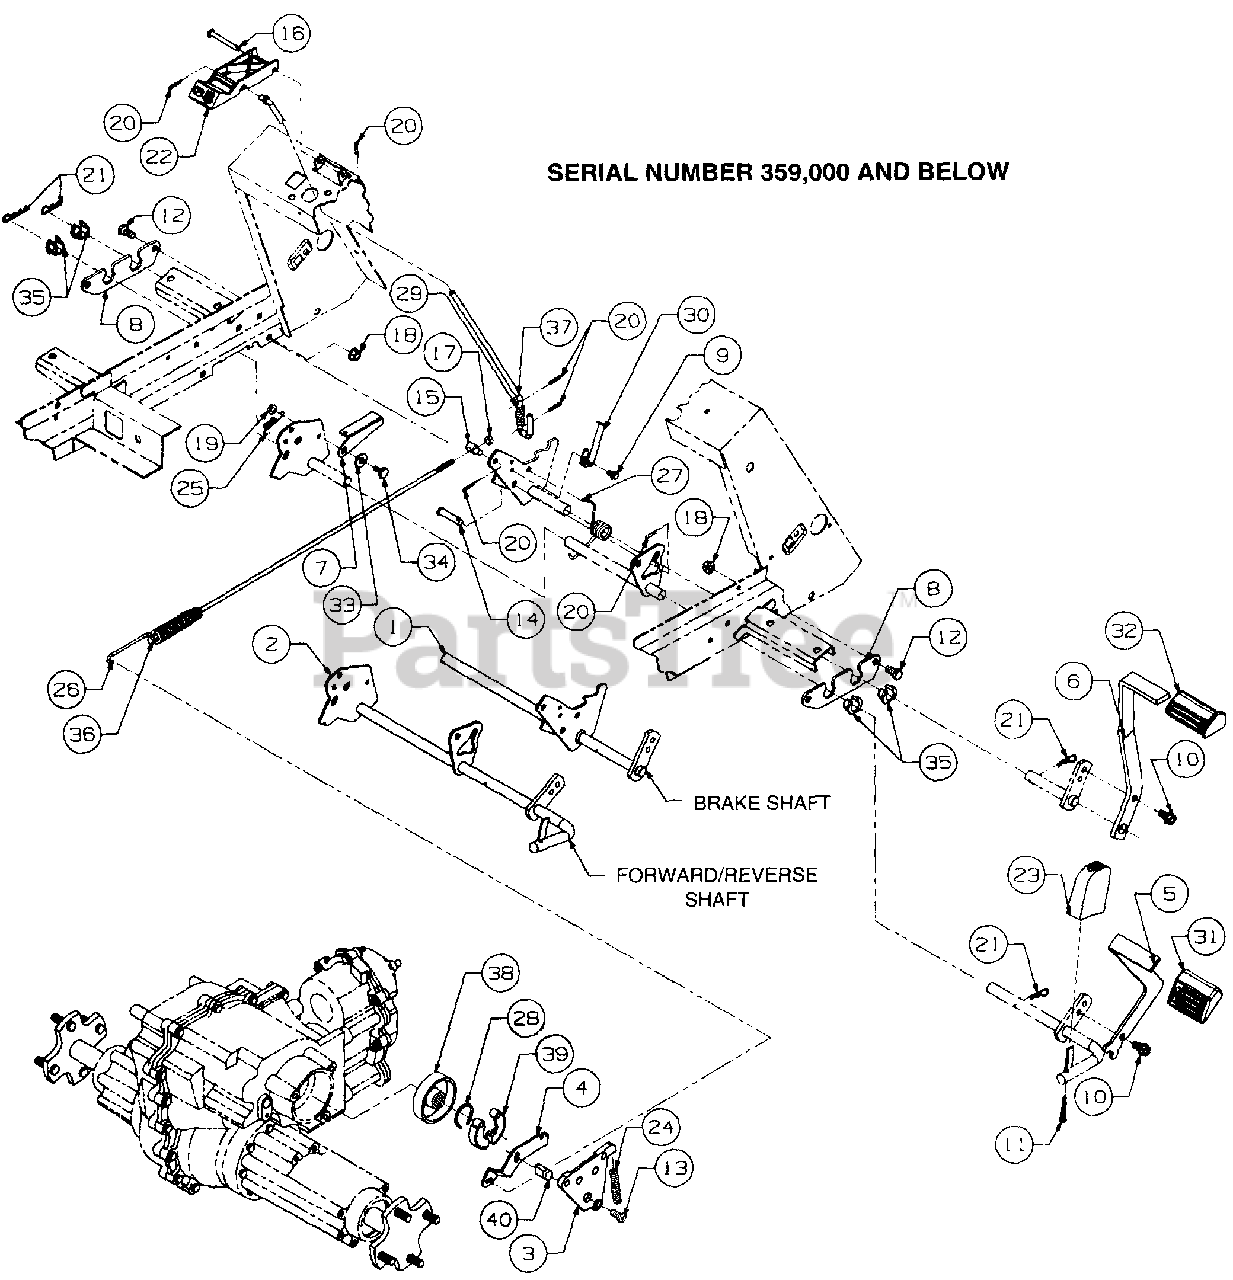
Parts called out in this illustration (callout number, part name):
1	Shaft Assy, Brake
2	Shaft Assy, Forward/Reverse
3	Plate, Brake
4	Arm, Brake
7	Actuator, Reverse Switch
8	Plate, Bearing Mounting
9	Screw, Hex Wash Tapp, 1/4 x .50 Lg
10	Screw, Hex Wash TT-Tapp, 3/8-16 x .75 Lg
11	Screw, Truss Mach Tapp, #12 x 1.5
12	Screw, Hex Cap, 3/8-16 x .75 GR5
13	Screw, Low Hd Cap, 3/8-16 x .75
14	Pin, Clevis, 3/8 OD x 1.62 Lg
15	Ferrule, Adjustment
16	Pin, Clevis, 1/4 OD x 2.38 Lg
17	Nut, Hex Sems, 1/4-20
18	Nut, Hex Flanged Lock, 3/8-16
19	Nut, Hex Flange Lock, 1/4-20
20	Pin, Internal Cotter, 5/16 Dia x 1.12
21	Pin, Internal Cotter, 3/8 Dia x 1.625
22	Lever, Park Brake
23	Pad, Reverse Pedal
24	Spring, Compression
25	Spring, Extension, .38 OD x 2.10 Lg
26	Spring, Extension, .75 OD x 5.0 Lg
27	Spring, Torsion
28	Spring, Brake
29	Spring, Compression, .5 OD x 2.23
30	Actuator, Neutral Switch
31	Pad, Forward Pedal
32	Pad, Brake Pedal
33	Washer, Flat, .406 x .75 x .063
34	Bolt, Shoulder, .375 Dia x .181 Lg
35	Bearing, Hex Flange Split
36	Rod, Brake
37	Rod, Park Brake Engagement
38	Drum, Brake
39	Shoe, Brake
40	Actuator, Brake Shoe
